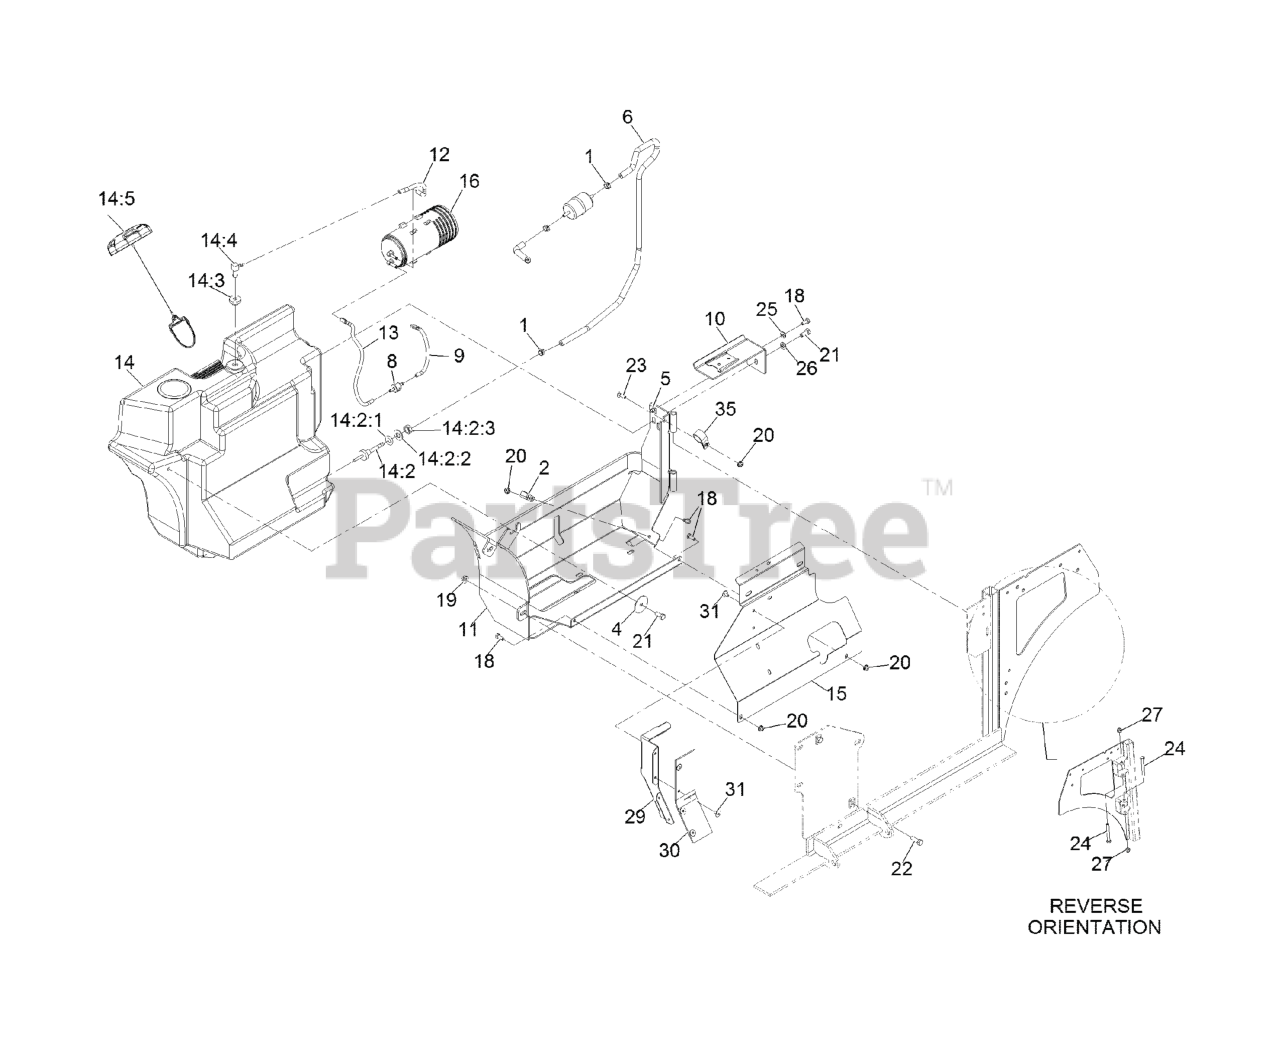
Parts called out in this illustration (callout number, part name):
1	CLAMP-HOSE
2	CLIP-LOOM
6	HOSE-FUEL
8	VALVE-CHECK, VACUUM
9	HOSE-VENT, FORMED
10	CANISTER BRACKET ASM
11	TANK FRAME ASM
12	HOSE-VENT, FORMED
13	HOSE-VENT, FORMED
14	FUEL TANK ASM
14:2	FITTING-FUEL, BULKHEAD
14:2:1	O-RING,BULKHEAD FITTING
14:2:2	WASHER-FLAT
14:2:3	NUT-JAM
14:3	BUSHING
14:5	CAP-FUEL, RATCHETING
15	PANEL-TANK SHIELD
16	CANISTER-CARBON, 800CC
18	SCREW-HH
21	SCREW-HH
22	SCREW-HH
23	BOLT-CARR
24	SCREW-HH
25	WASHER-FLAT
26	WASHER-PLAIN
27	NUT-LOCK, NI
29	DEFLECTOR-AIR
30	FLAP-RUBBER
31	RIVET-POP
35	R-CLAMP
